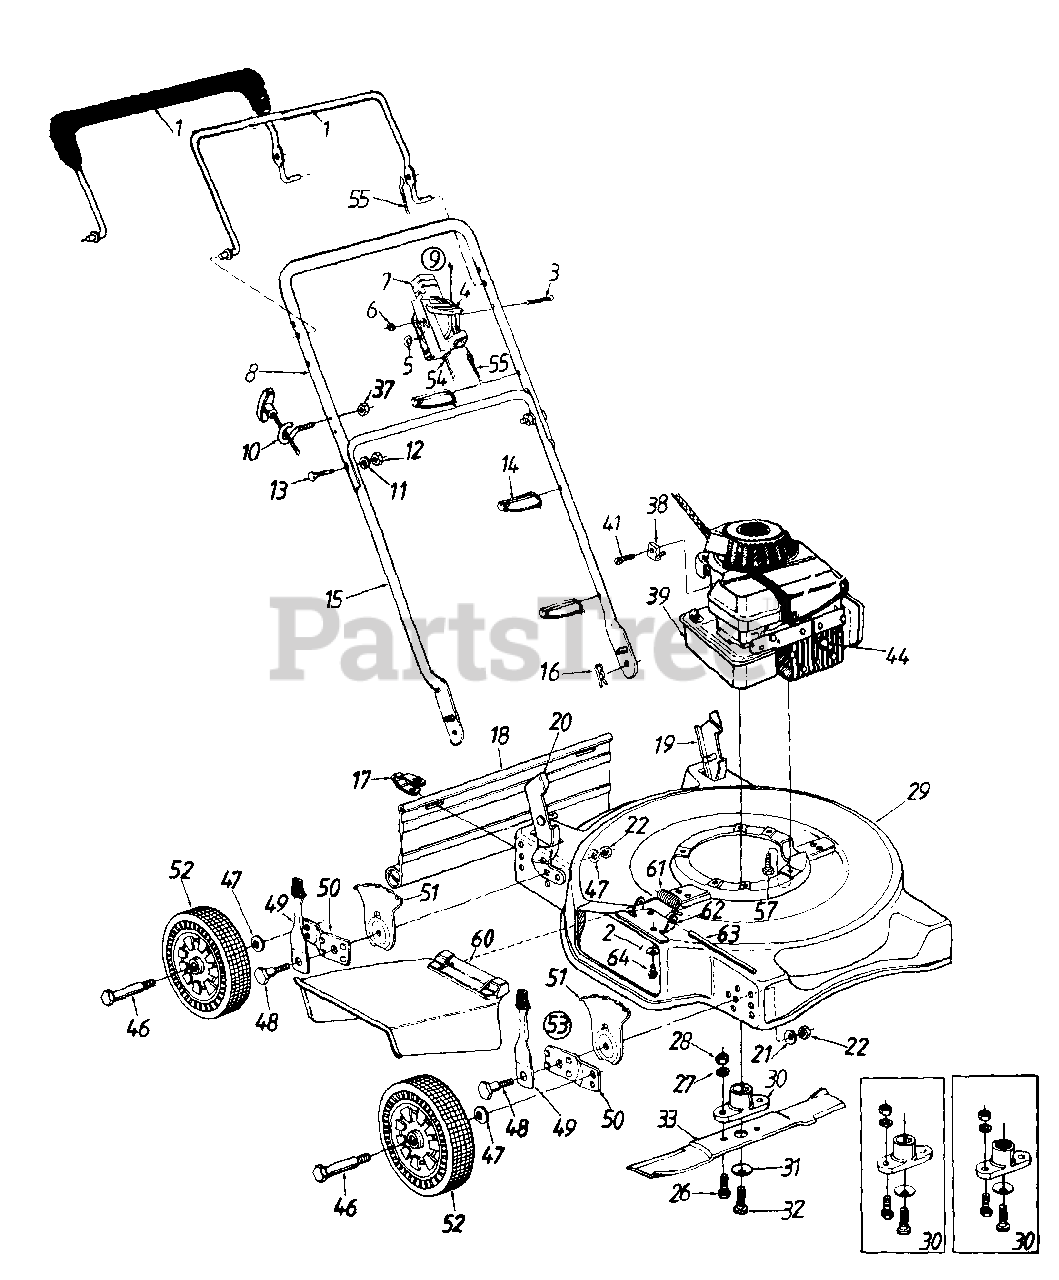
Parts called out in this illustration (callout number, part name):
2	Bell-Wash. 1/4" I.D.
3	Oval C-Sunk Mach. Scr.
4	Throttle Lever
5	Spr. Wash..66" I.D.
6	Hex L-Nut 1/4-20 Thd.
7	Throttle Body
10	Rope Guide
11	L-Wash. 5/16" I.D.
12	Hex Nut 5/16-18 Thd.
13	Curved Carriage Bolt 5/16-18 x 1.38" Lg.
14	Cable Tie
15	Lower Handle
16	Hairpin Cotter
17	Hinge Clip
18	Rear Flap
19	Handle Bracket Ass'y.- L.H.
20	Handle Bracket Ass'y.- R.H.
21	Bell-Wash..39" I.D. x 1.38"
22	Hex Nut 3/8-16 Thd.
26	Hex Bolt 3/8-24 x 1" Lg.
27	L-Wash. 3/8" I.D.
28	Hex Nut 3/8-24 Thd.
30	Blade Adapter Kit
31	Bell-Wash..39" I.D.
32	Hex Bolt 3/8-24 x 1.5" Lg.
33	20" Blade
37	Hex L-Nut 1/4-20 Thd.
38	Cable Clamp
39	Engine
41	Hex Wash. Hd. Tap Scr. #10-32 x .62" Lg.
44	Spark Plug Boot
46	Axle Bolt
47	Bell-Wash..400" I.D. x .88"
48	Shld. Bolt .50" Dia. x .357"
49	Spring Lever Ass'y. w/Knob
51	Height Adj. Plate
52	Wheel Ass'y. Comp. Diamond Tread (7")
53	Height Adj. Ass'y. Comp.- R.F. & L.R.
54	Throttle Control Wire - 51" Lg.
55	Control Cable - 39" Lg.
57	Hex L-Wash. Hd. Scr. 3/8-16 x 1.0" Lg.
60	Chute Deflector Ass'y.
61	Torsion Spring
62	Adapter Plate
63	Hinge Pin
64	Hex Self-Tap Scr. 1/4-20 x .5" Lg.
